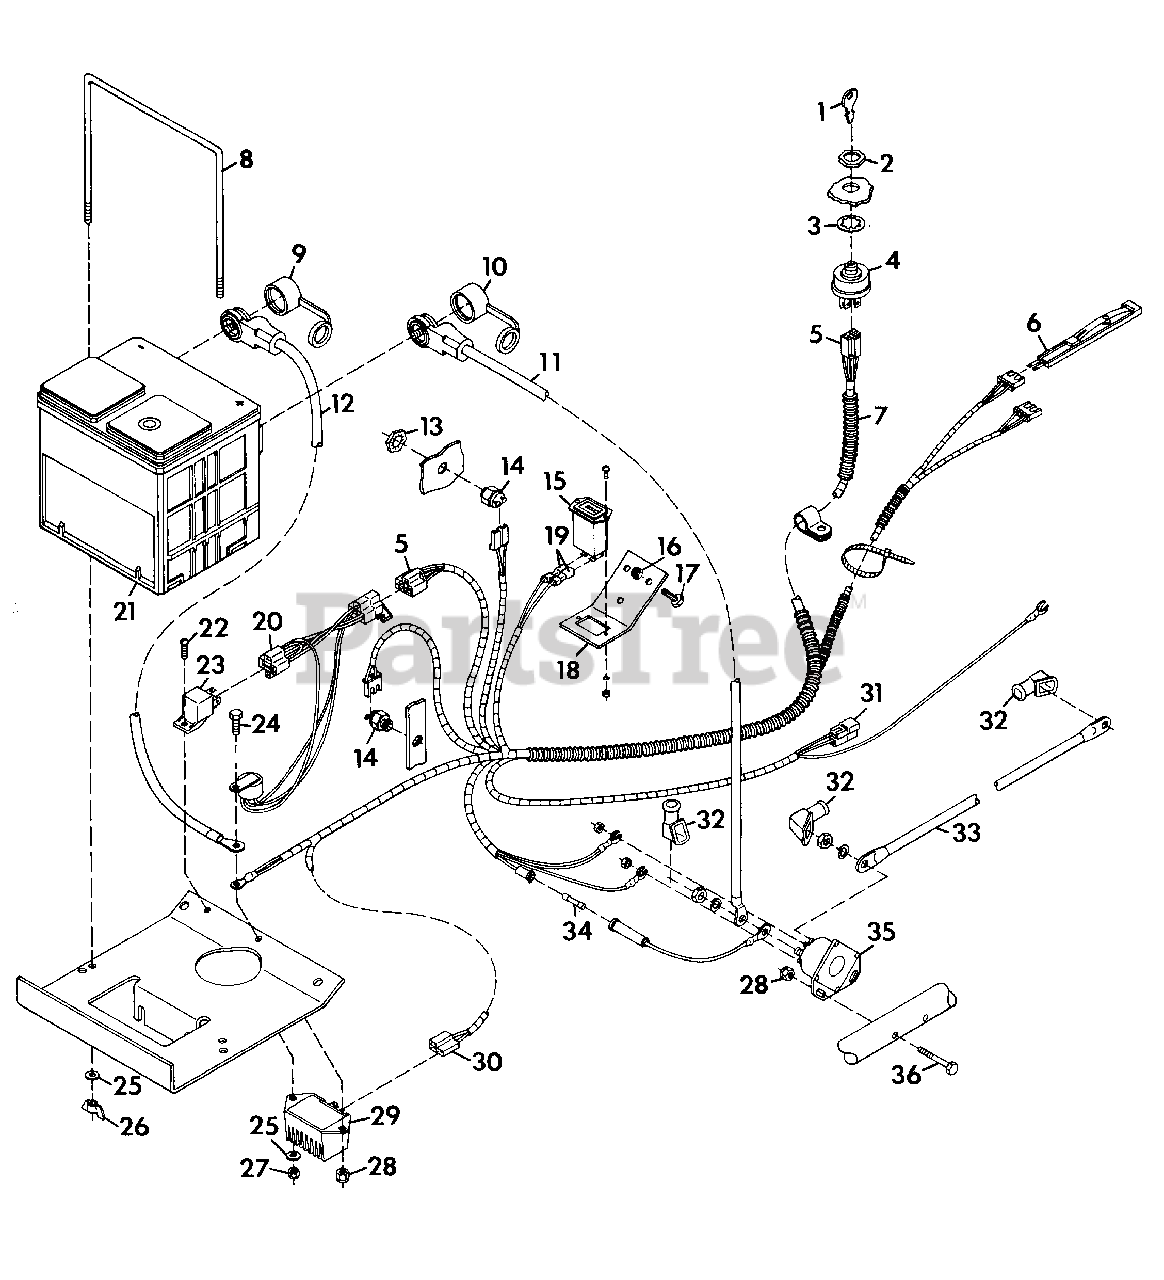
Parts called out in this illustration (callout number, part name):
1	KEY, IGNITION
2	NUT, JAM 9/16-24
3	WASHER, LOCK
4	SWITCH, IGNITION
5	CONNECTOR
6	SWITCH, SEAT
7	HARNESS, PRO MASTER-50
8	ROD, BATTERY
9	COVER, BATTERY NEG.
10	COVER, BATTERY POS.
11	CABLE, ELECTRICAL
12	CABLE, ELECTRICAL
13	NUT, STAMPED 9/16-18
14	SWITCH, INTERLOCK
15	HOURMETER
16	NUT, LOCK 3/8-16
17	BOLT, HEX 3/8-16X.875
18	BRACKET, HOURMETER
19	TERMINAL
20	MODULE, TIME DELAY
21	BATTERY, DELCO MAINTENANCE-FREE #101 -REPLACEMENT BATTERY #83-50
22	SCREW, MACH. 10-24X1.00 RD HD
23	RELAY
24	BOLT, HEX 1/4-20X1.00
25	WASHER, FLAT .281X.625X.065
26	NUT, WING 1/4-20
27	NUT, LOCK 10-24
28	NUT, LOCK 1/4-20
29	REGULATOR, RECTIFIER
30	CONNECTOR
31	CONNECTOR
32	BOOT, BATTERY CABLE
33	CABLE
34	FUSE, 30 AMP
35	SWITCH, MAGNETIC
36	BOLT, HEX 1/4-20X2.00
